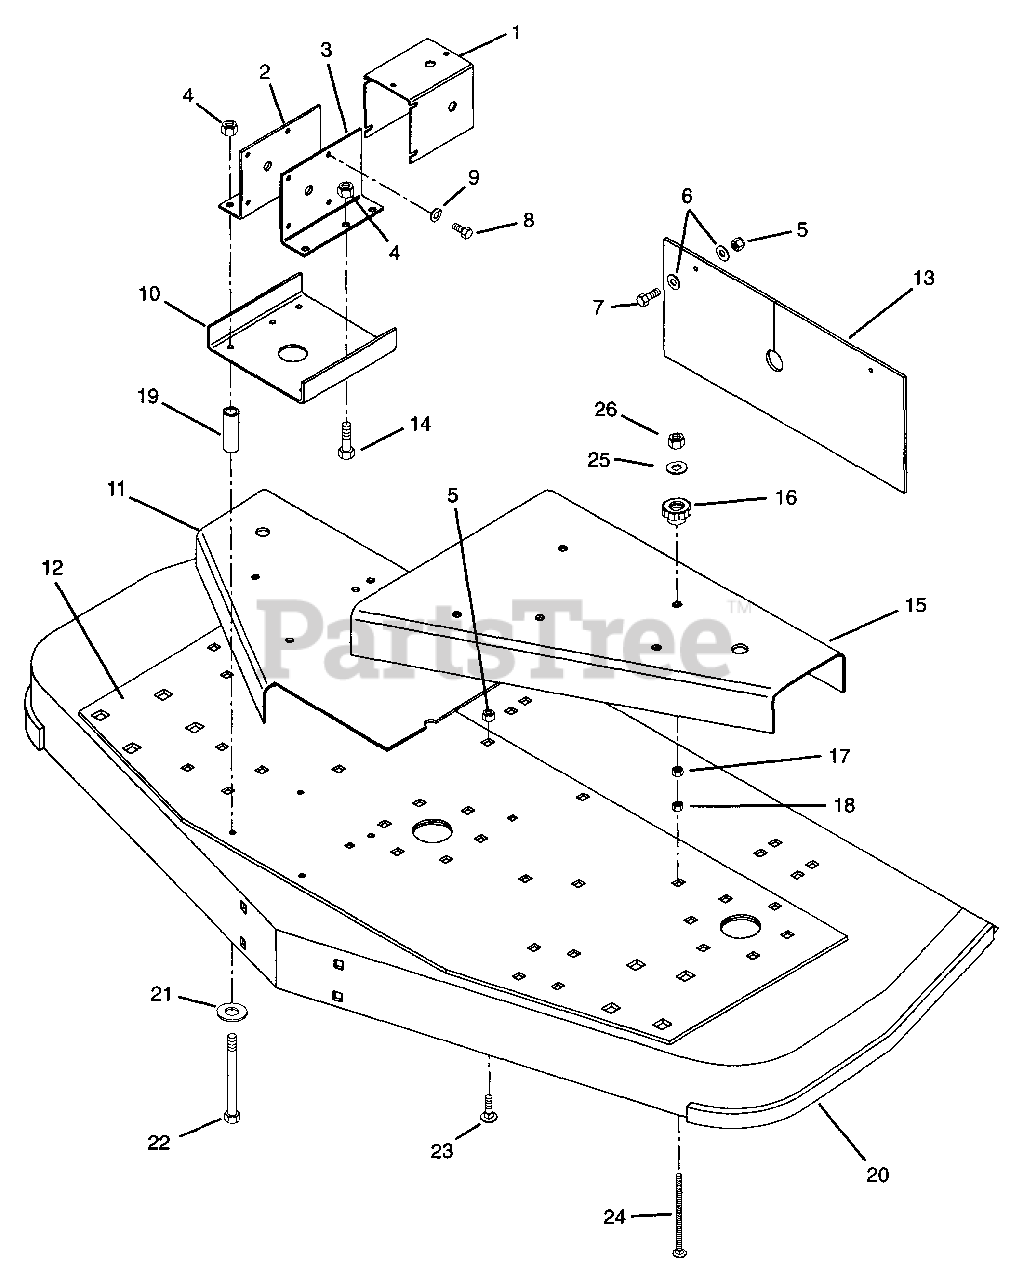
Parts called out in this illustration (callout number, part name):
1	Shield, U-Joint
2	Bracket, Gearbox Mounting Right Hand
3	Bracket, Gearbox Mounting Left Hand
4	Nut-Locking-Nylon .50-13 Grade 5
5	Nut-Locking-Nylon .375-16 Grade 2
6	Washer-Flat-Steel .406 x .812 x .065
7	Bolt-Hex .375-16 x 1.00 Grade 5
8	Bolt-Hex .380-16 x .875
9	Washer-Lock .375 x .094
10	Plate, Support
11	Cover, Belt Right Hand
12	Plate, Deck Support
13	Shield Grass
14	Bolt-Hex .50-13 x 1 Grade 5
15	Silkscreen, Belt Cover
16	Knob
17	Nut-Locking-Nylon .312-18 Grade 2
18	Nut-Jam .312-18
19	Spacer .562 x 1.00 x 2.00
20	Weldment, 72" Rear Discharge Deck
21	Washer-Flat-Steel .531 x 1.062 x .095
22	Bolt-Hex .50-13 x 3.75
23	Bolt-Round Head Square Neck .38-16 x 1.0
24	Bolt-Round Head Square Neck .31-18 x 4.0
25	Washer-Flat-Steel .323 x .625 x .062
26	Nut-Locking-Nylon .312-18 w/ Insert Grade 2
